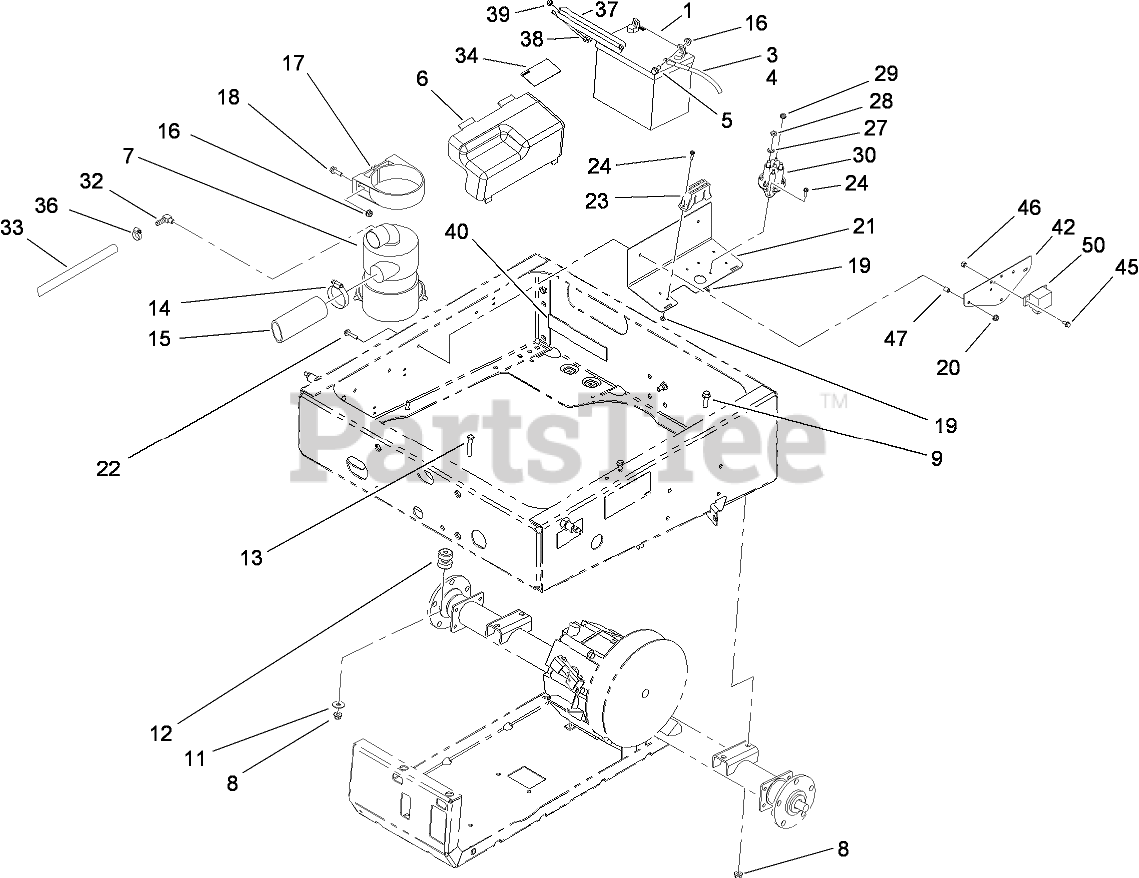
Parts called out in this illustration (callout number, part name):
1	BATTERY-DRY
3	CABLE-NEGATIVE
4	CABLE-POSITIVE
5	SCREW-HHF
6	COVER-ELECTRICAL
7	AIR CLEANER ASM
8	NUT-HF, NI
9	SCREW-HHF
11	WASHER-FLAT
12	MOUNT-ISO
13	SCREW-HH
14	CLAMP-HOSE
15	HOSE-INTAKE
16	NUT-HF, NI
17	BRACKET-MOUNTING
18	SCREW-HHF
19	NUT-LOCK, NI
20	NUT-HHF
21	MOUNT-COMPONENT
22	SCREW-HHF
23	HARNESS-WIRE, MAIN
24	SCREW-HWH
27	WASHER-LOCK
28	NUT-JAM
29	NUT-KEPS
30	SOLENOID
32	FITTING-90 DEG
33	HOSE-BREATHER
34	DECAL-INFORMATION
36	CLAMP-HOSE
37	CLAMP-BATTERY
38	HOOK-RETAIN, BATTERY
39	NUT-HF
40	Pad-Battery
42	BRACKET-IGNITION
45	SCREW-HHF
46	NUT-LOCK, NI
47	SPACER
50	RELAY
